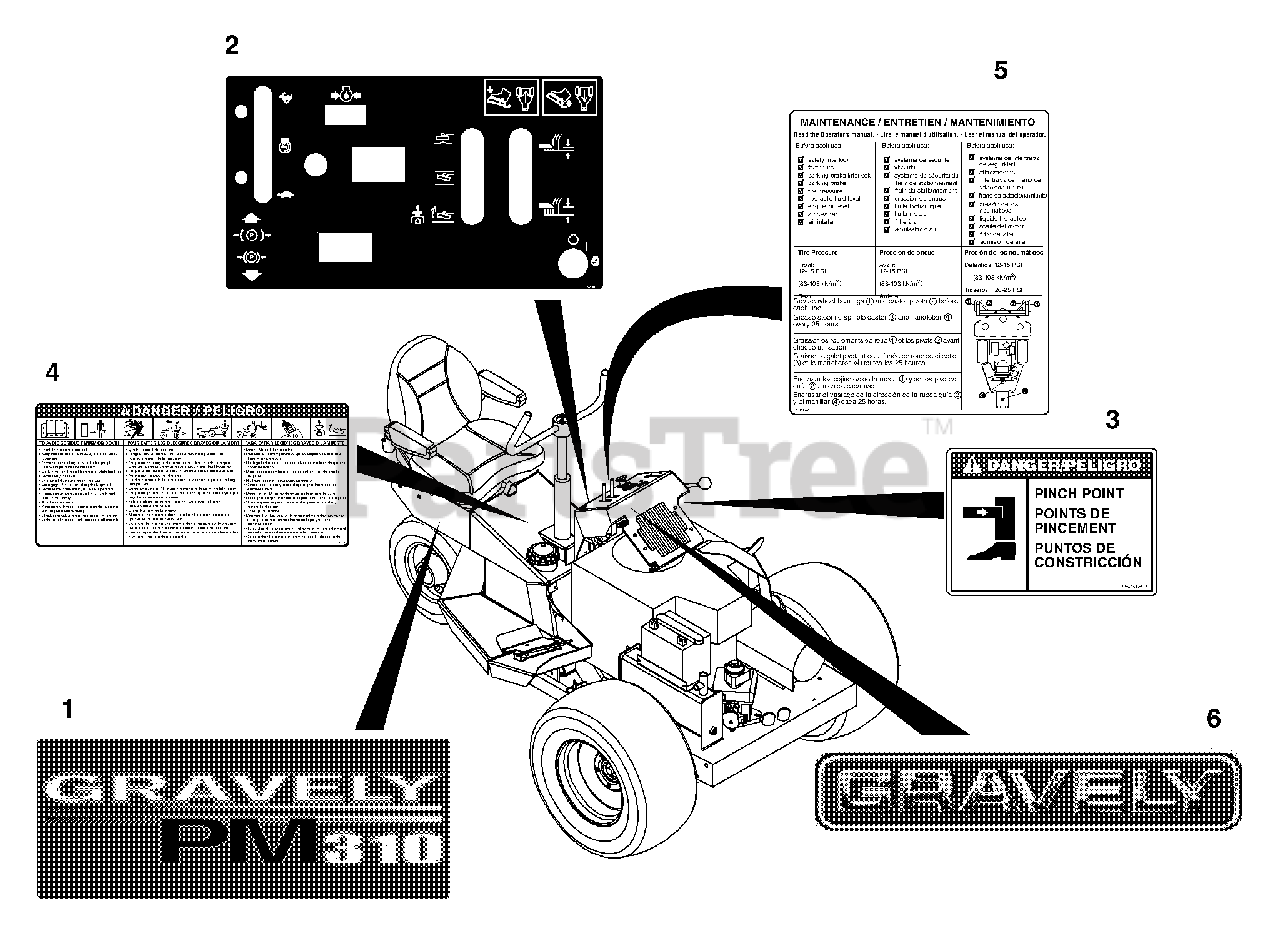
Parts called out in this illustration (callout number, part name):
1	Decal, PM-310
2	Decal, PM-310 Panel
3	Decal, Pinch Point
4	Decal, PM-310 Danger
5	Decal, PM-310 Maintenance
6	Decal, Gravely Logo
